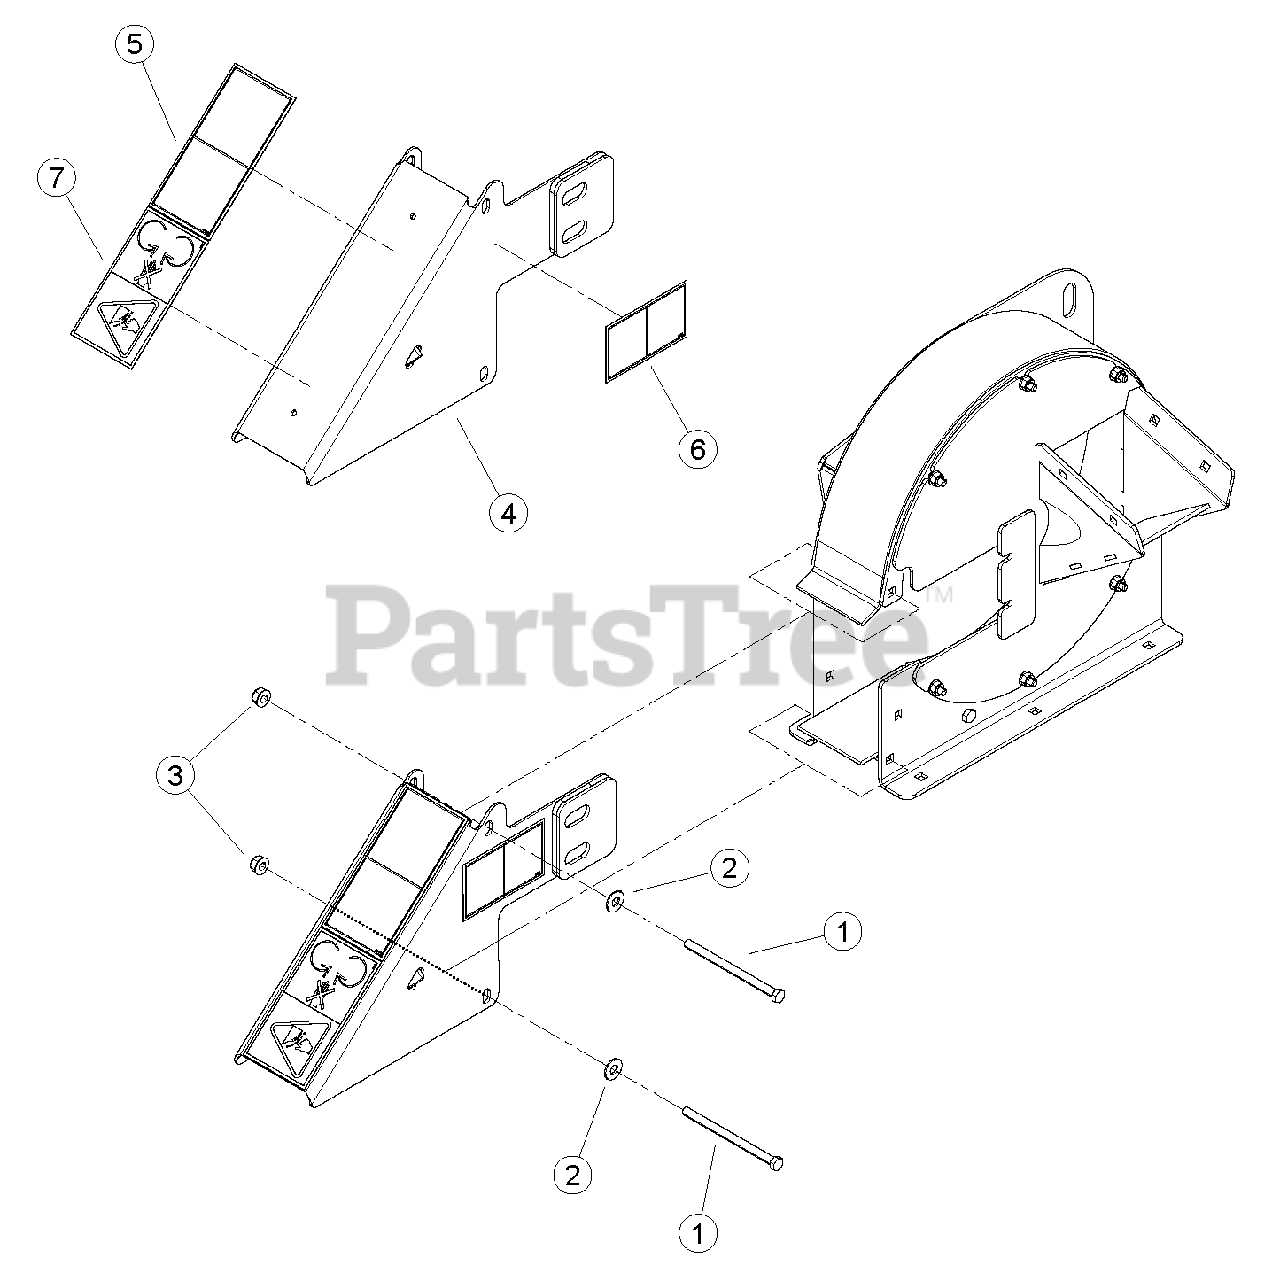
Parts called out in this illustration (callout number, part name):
1	BOLT, 3/8 X 5-1/2 HEX GR5 ZP
2	WASHER, 3/8" FLAT ZP
3	NUT, 3/8-16 NYLOCK FLANGE
4	ASSEMBLY, DISCHARGE CAP
5	DECAL, KNIFE ACCESS ISO
6	DECAL, DISCHARGE ISO
7	DECAL, BLADE DANGER ISO
